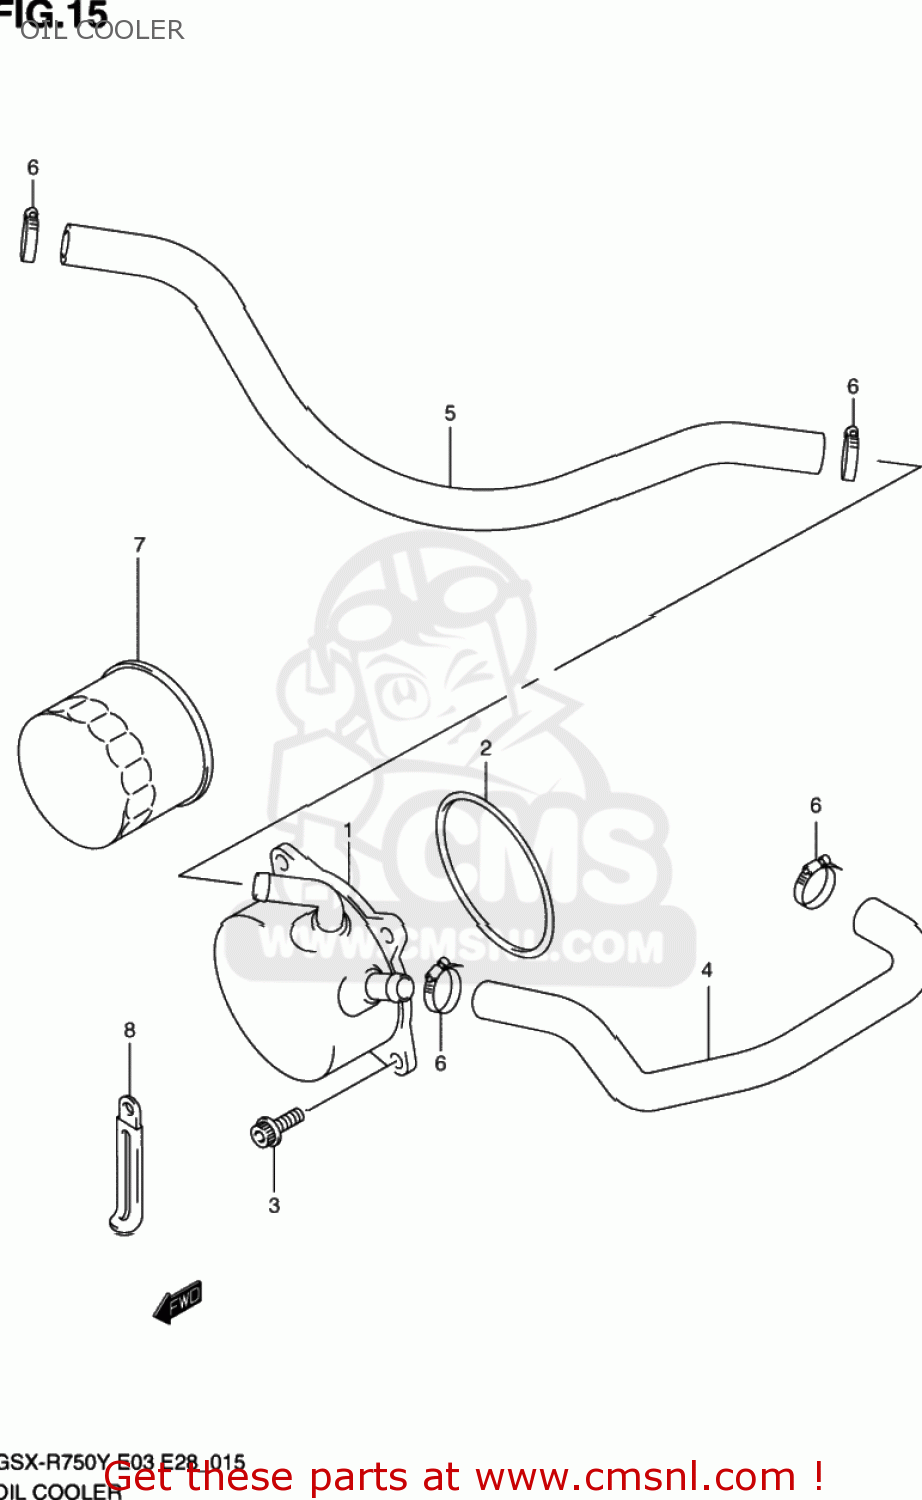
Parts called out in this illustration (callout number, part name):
1	COOLER ASSY,OIL
2	O RING(D:3.1,ID:63.9)
3	BOLT(6X16)
4	HOSE,OIL COOLER WATER INLET
5	HOSE,OIL COOLER WATER OUTLET
6	CLAMP
7	FILTER ASSEMBLY,ENGINE OIL
8	CLAMP(L:80)
